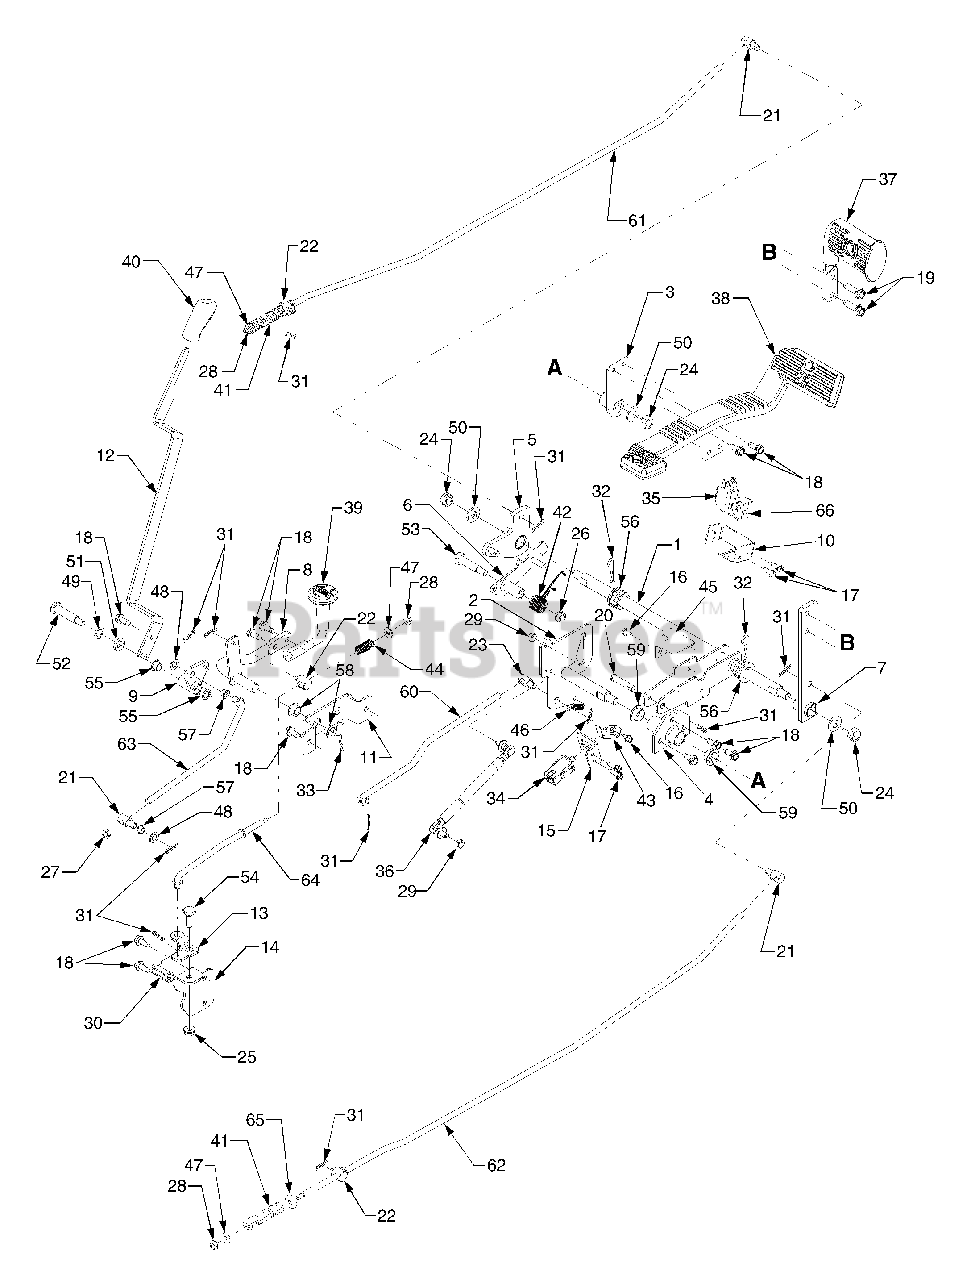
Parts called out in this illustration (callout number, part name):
1	Shaft Assembly, Brake
2	Shaft Assembly, Forward
3	Link Assembly, Pedal
4	Plate, Bearing
5	Link Assembly, Brake LH
6	Link Assembly, Parking Brake
7	Link Assembly, Brake RH
8	Shaft Assembly, Differential
9	Link, PTO Select
14	Bracket, Diff. Actuator Mtg.
17	Screw, Hex Wash Hd Tapp 1/4-20 x .75
18	Screw, Hex Wash Hd Tapp 5/16-18 x .75
19	Screw, Hex Wash Hd Tapp 3/8-16 x 1.0
20	Pin, Clevis, 3/8 x 1.75
21	Ferrule, 3/8-24 x .375 Dia. Hdn
22	Ferrule, Brake
23	Ferrule, 3/8-24 x .37
24	Nut, Hex Lock, 1/2-20
25	Nut, Hex Flange Lock, 3/8-24
26	Nut, Hex Flange Lock, 3/8-16
27	Nut, Hex Jam, 3/8-24
28	Nut, Hex Flange Lock, 1/4-20
29	Nut, Hex, M8 x 1.25 GR8.8
30	Link, Chain
31	Pin, Internal Cotter
32	Pin, Internal Cotter
33	Pin, Internal Cotter
34	Switch, Plunger
35	Switch, 3-Pole Plunger - Brake
36	Cylinder, Damper
37	Pedal, Brake
38	Pedal, Forward/Reverse
39	Pedal, Differential
40	Grip, Handle
41	Spring, Compression
42	Spring, Torsion
43	Spring, Rev/No Cut
44	Spring, Compression
47	Washer, Flat, .28 x .74 x .063
48	Washer, Flat, .375 x .738 x .063
49	Washer, Wave, .53 x .78 x .013
50	Washer, Flat, .53 x .1.06 x .134
51	Washer, Flat, .53 x .875 x .15
52	Screw, Shoulder, .50 x 1.825
53	Screw, Shoulder, .498 x 1.635
54	Screw, Shoulder 1/2 x .180: 3/8-24
55	Bearing, Nylon. .50 ID x .341
56	Bearing, Hex Flange, .752 ID
57	Bearing, Flange, .375 x .58 x .25
58	Bearing, Flange .626 x .938 x .344
59	Bearing, Flange .751 x 1.125 x .375
60	Rod, Hydro Control
61	Rod, Brake, LH
62	Rod, Brake, RH
63	Rod, PTO Control
64	Rod, Diff. Lock Control
65	Washer, Flat, .38 x .93 x .11 HT
66	Switch, Brake Light
